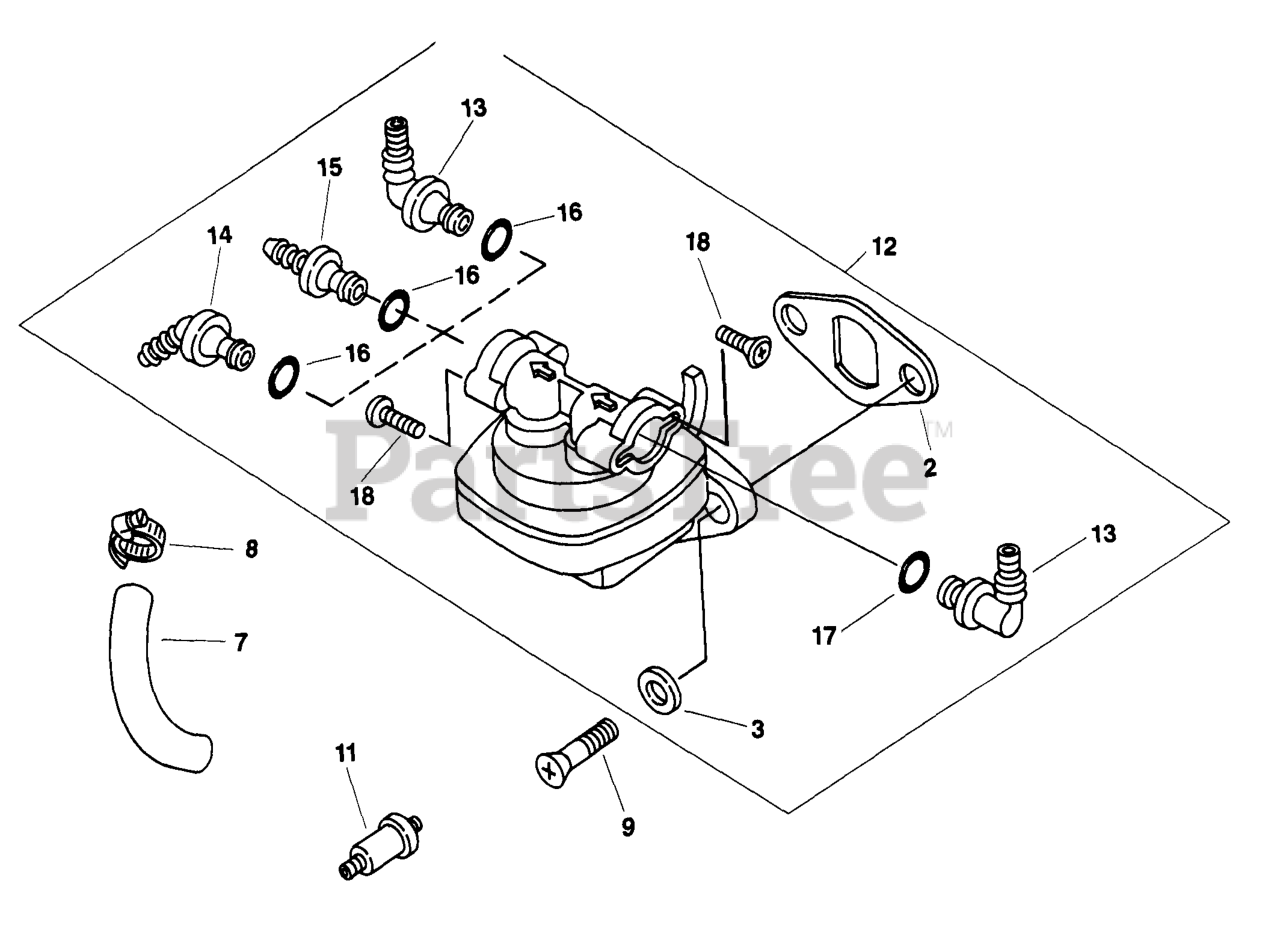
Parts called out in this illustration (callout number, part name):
2	GASKET - USE 25 041 09
3	WASHER, FLAT 1/4" (O.D. 1/2")
9	SCREW, SEMS 1/4-20X3/4"
11	FILTER - USE 41 050 03
12	PUMP - USE 47 559 04-S
13	CONNECTOR, 90 DEG. W/O-RING-DISC.
14	CONNECTOR, 45 DEG. W/O-RING-DISC.
15	CONNECTOR,STRAIGHT W/O-RING-DISC.
16	O RING FITTING - DISCONTINUED
17	SCREW, LBD SCKT PAN - DISC.
